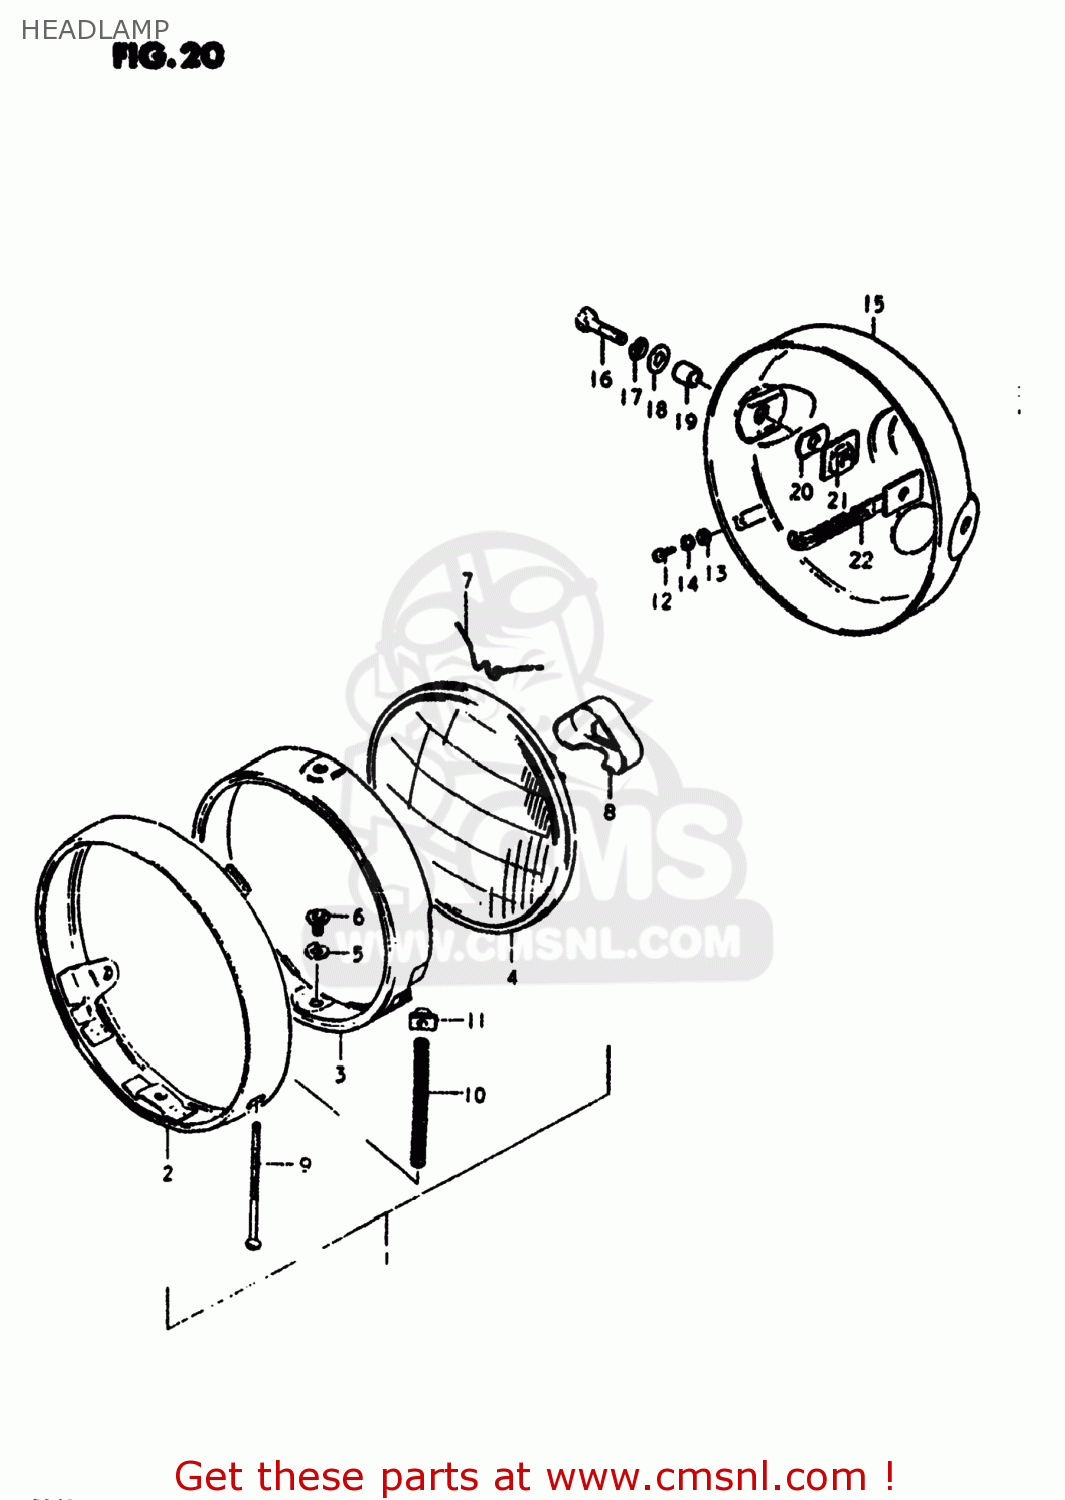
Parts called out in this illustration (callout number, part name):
1	HEADLAMP ASSEMBLY
2	RIM,HEADLAMP
3	RETAINER
4	LAMP UNIT
5	LOCK WASHER
6	SCREW
7	SPRING,HEAD LAMP UNIT
8	COVER
9	SCREW
10	SPRING,HEADLAMP ADJUST
11	NUT
12	SCREW
13	WASHER
14	LOCK WASHER
15	HOUSING,HEADLAMP
16	BOLT
17	LOCK WASHER
18	WASHER
19	SPACER (8.8X12X7)
20	CUSHION
21	PLATE,HEADLAMP HOUSING
22	PLATE,HEADLAMP HOUSING
